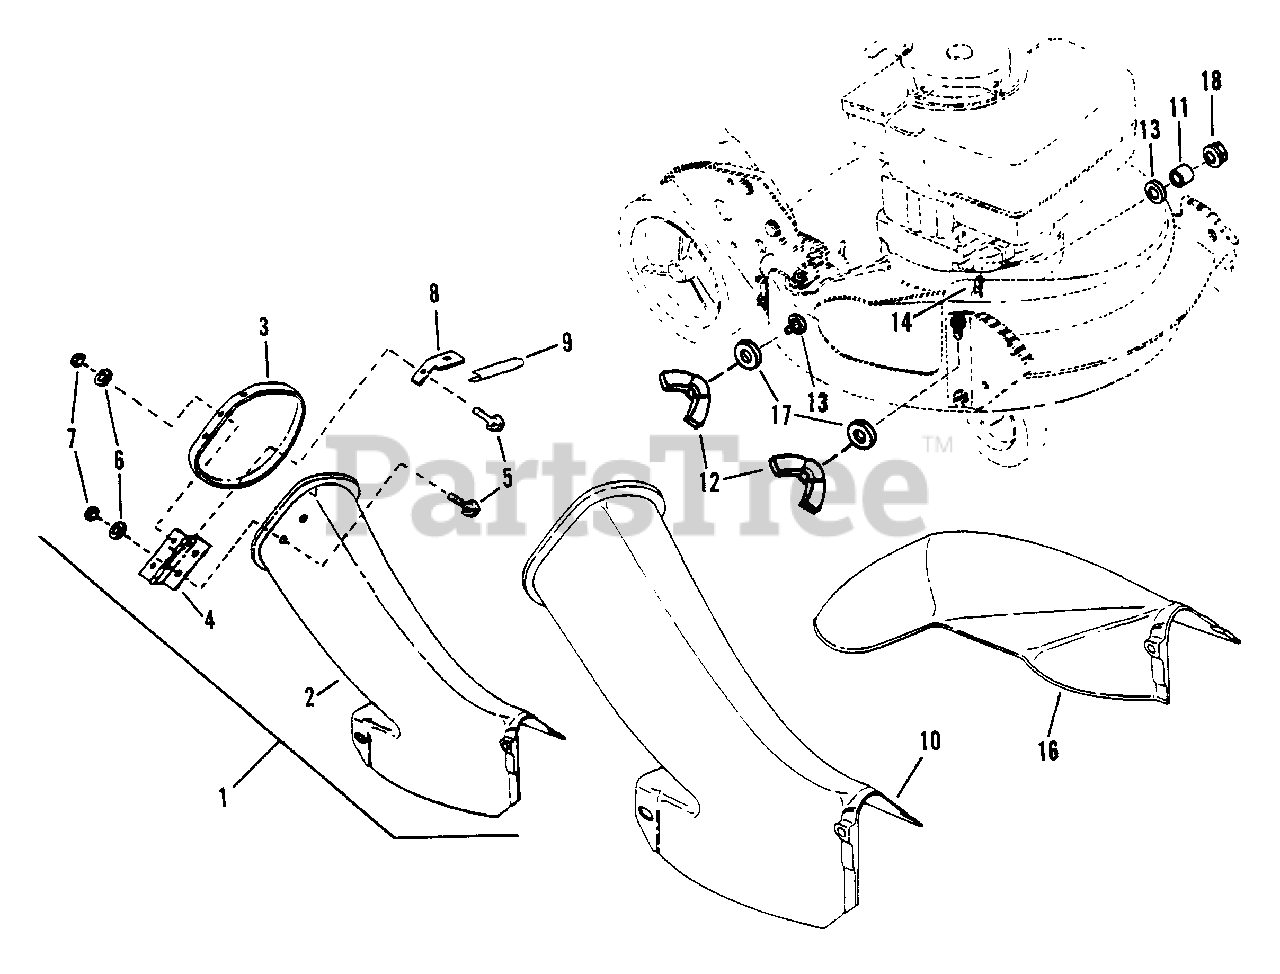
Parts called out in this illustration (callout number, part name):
1	ASSEMBLY, Bag Adapter & Cover
2	ADAPTER, Grass Bag
3	COVER, Bag Adapter
4	HINGE, Chute Cover
5	BOLT, 1/4-20 x 1/2" Short Neck Carriage
6	WASHER, 1/4 Internal Tooth Lock
7	NUT, 1/4-20 Hex
8	STOP, Cover
9	MOLDING, Trim
10	ADAPTER, Grass Bag
11	SPACER
12	NUT, 5/16-18 Wing (Nylon Patch)
13	RETAINER, 5/16 Bolt
14	BOLT, 5/16-18 x 3/4 Short Neck Carriage
16	CHUTE, Side
17	WASHER, 5/16 Flat
18	NUT, 5/16-18 Hex Flange Lock
